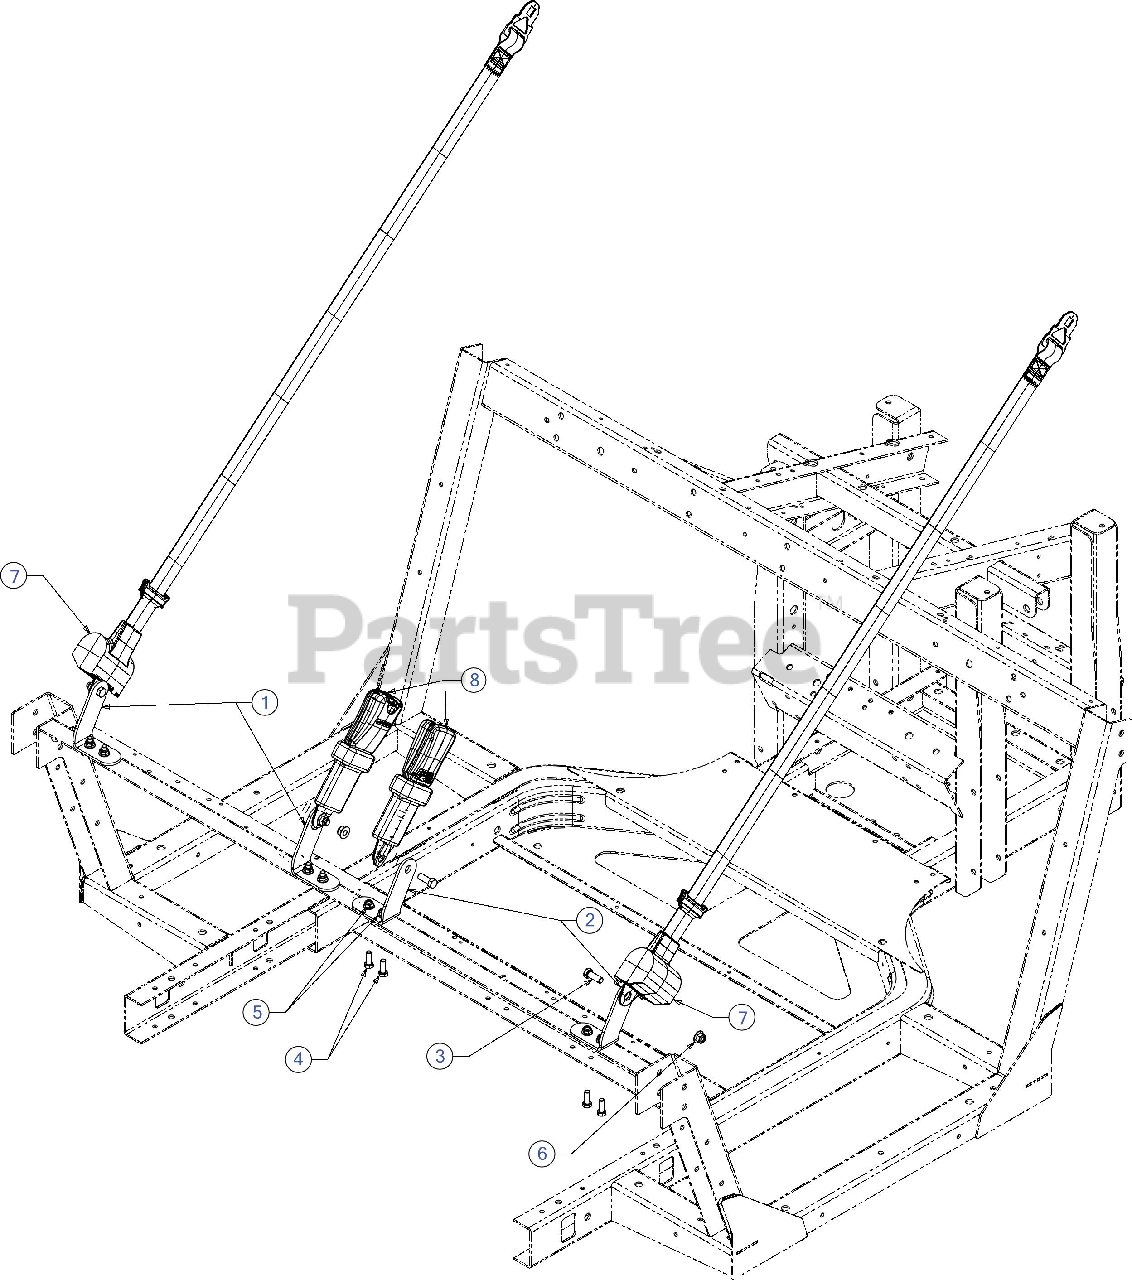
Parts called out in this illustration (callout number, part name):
1	SEAT BELT BRACKET
2	SEAT BELT BRACKET
3	SCREW 3/8-16 x 1 GR5
4	SCREW 5/16-18 x .875 GR5
5	FLANGE LOCK NUT 5/16-18
8	3-POINT SEAT BELT
